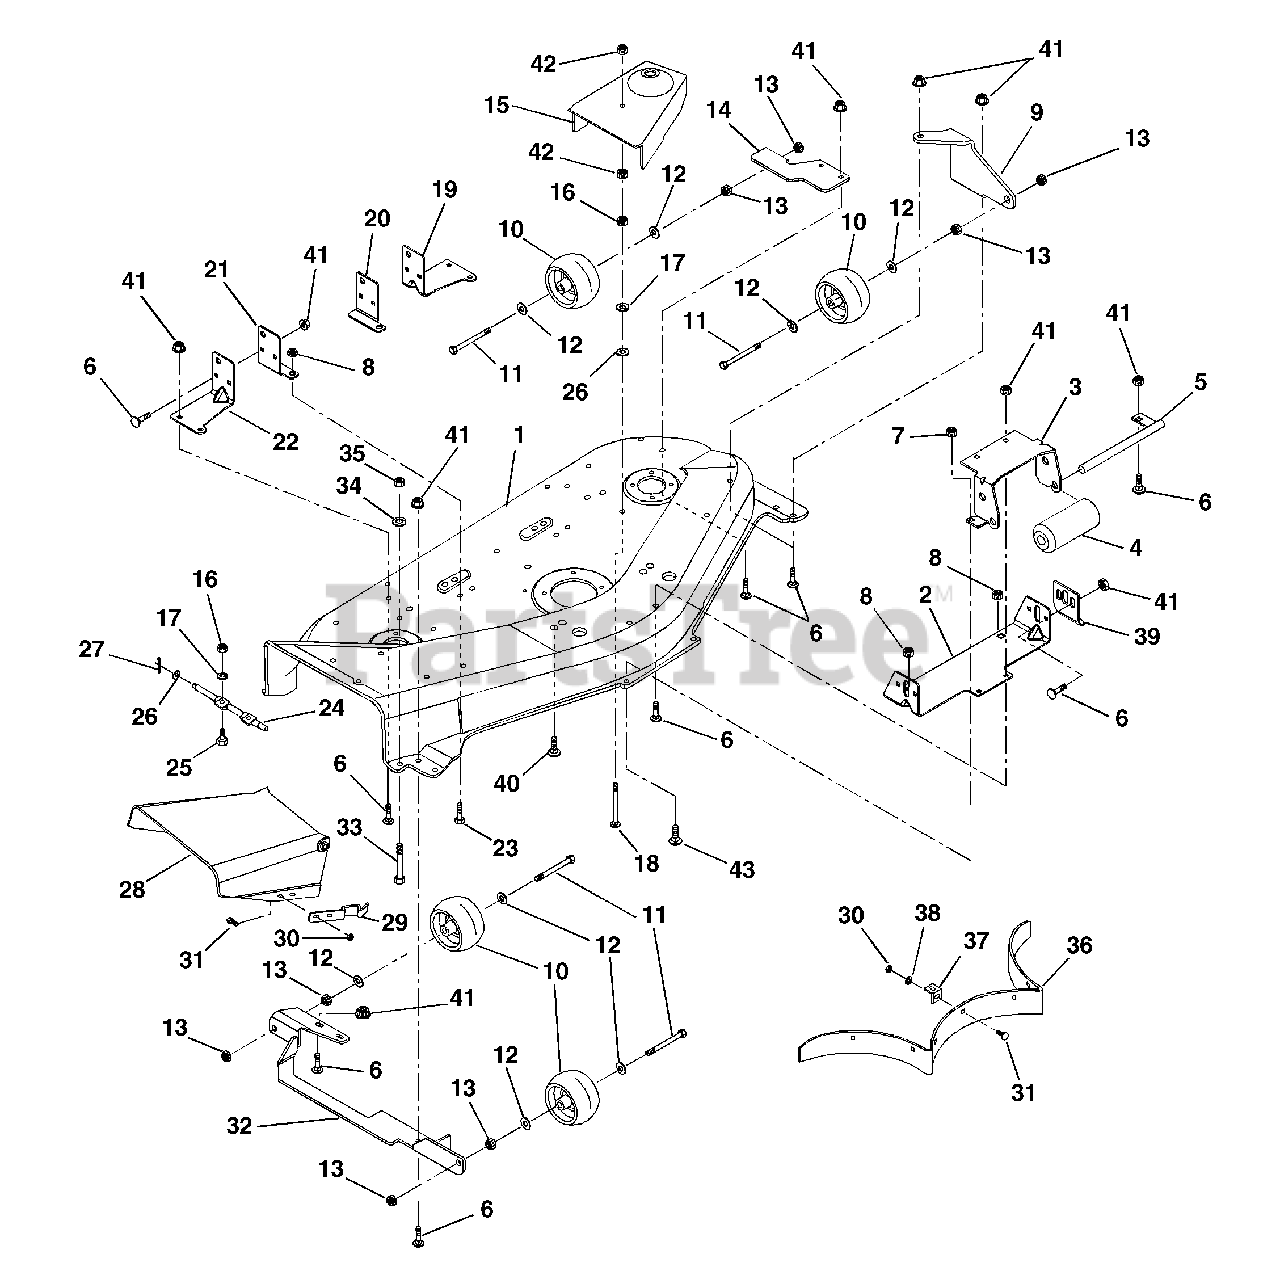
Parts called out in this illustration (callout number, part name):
1	48" DECK W/DECALS - GLT
2	FRONT HANGER
3	BRACKET, ROLLER
5	ROLLER SHAFT
6	@BLT-RDHDSQNK .31-18X.75 G5YZ
7	@NUT-LK-CTR .31-18 YWZC
8	@NUT-LK-TOP-FLG .50-13 YWZC
9	BRACKET, LEFT FRONT
10	WHEEL 5 X 3
11	@BLT-HEX .50-13X4.00 GR5 YWZC
12	WSHR-FL-STL .505X.880X.072 YWZ
13	NUT-LK-CTR-JAM .50-13 YWZC(ND)
14	BRACKET, LEFT REAR
15	COVER, RIGHT HAND
15	COVER, LEFT HAND
16	@NUT-HEX .31-18 YWZC
17	@WSHR-LK .31X.078 REG YWZC
18	BLT-RDHDSQNK .312-18X3.25 YWZC
19	LH REAR HANGER
20	LH REAR HANGER SUPPORT
21	RH REAR HANGER SUPPORT
22	RH REAR HANGER
23	@BLT-HEX .50-13X1.00 GR5 YWZC
24	HINGE PIN
25	@BLT-HEX .31-18X.75 GR5 YWZC
26	@WSHR-FL-STL.406X.812X.065 YWZ
27	@PIN-CTR .09X.75 EXTPRSQCT YWZ
28	CHUTE EXTENSION
29	FLAT SPRING - ORANGE
30	@NUT-LK-CTR .25-20 YWZC
31	@BLT-RDHDSQNK .25-20X.50 G5YZ
32	MOUNT ROLLER
33	@BLT-RDHDSQNK .38-16X2.50 G5YZ
34	WSHR-LK .375X.130 YWZC
35	@NUT-HEX .38-16 YWZC
36	BAFFLE
37	BAFFLE TAB
38	@WSHR-FL-STL.281X.62X.065 YWZC
39	MOWER ADJUSTMENT TAB
40	@BLT-RDHDSQNK .50-13X1.00 G5YZ
41	@NUT-LK-TOP-FLG .31-18 YWZC
42	@NUT-LK-CTR .31-18 YWZC
43	@BLT-RDHDSQNK .31-18X1.00 G5YZ
